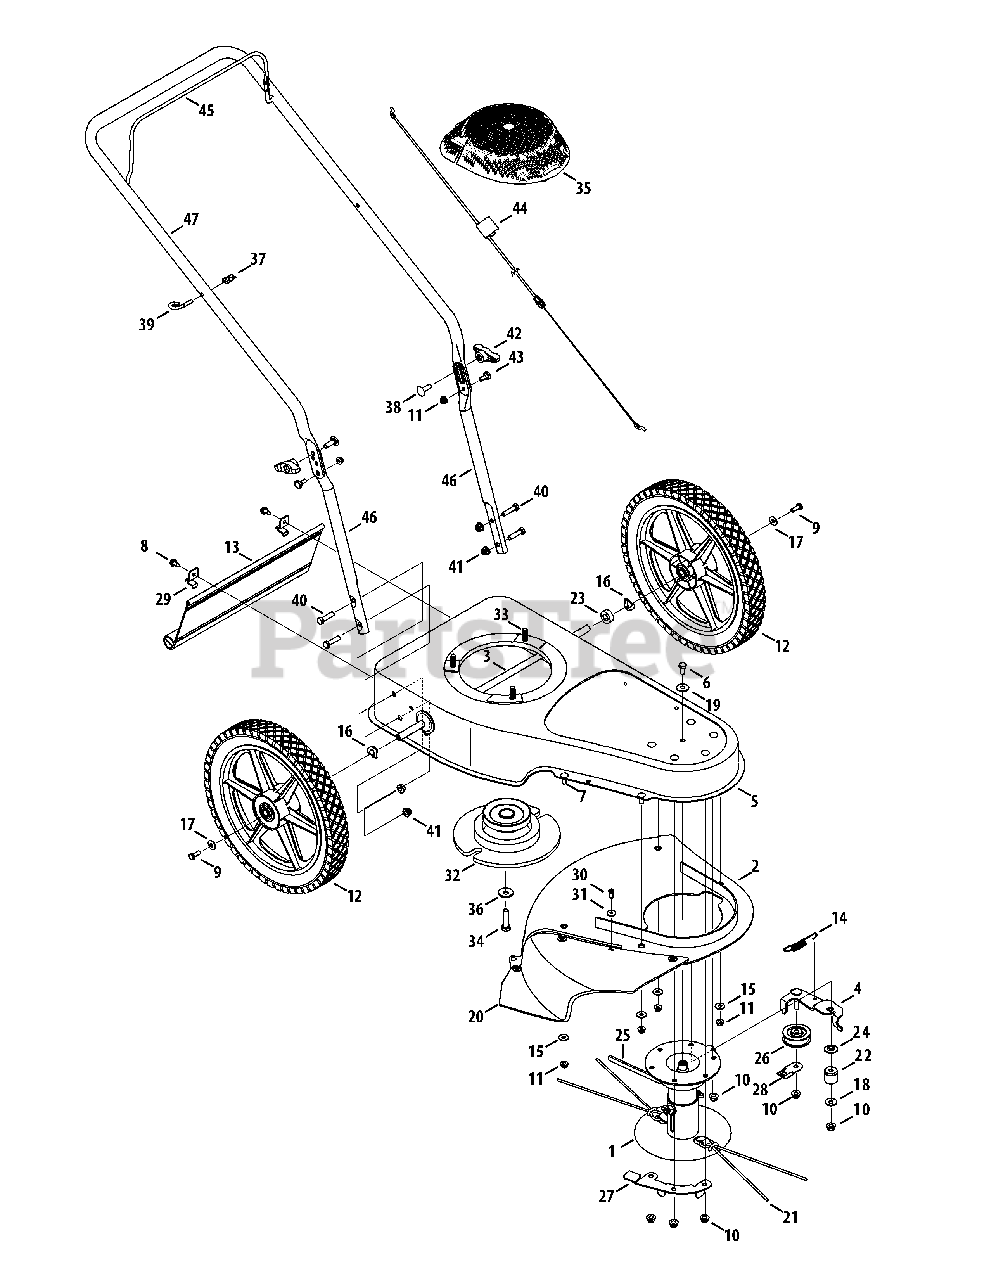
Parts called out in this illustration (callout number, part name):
1	Spindle Assembly
2	Deflector Assembly, Trimmer
3	Axle Assembly, Trimmer
4	Bracket Assembly, Idler Trimmer
5	Deck Assembly, Trimmer
6	Hex Screw, 5/16-24, .625, Gr5, Std
7	Screw, Carriage, 1/4-20, .75, Gr5
8	Screw, Self-tapping, 1/4-20 x .625
9	Hex Screw, 1/4-20, .75, Gr5, Std
10	Nut, Flange Lock, 5/16-18, GrF
11	Nut, Flange Lock, 1/4-20, GrF
12	Wheel, 14 x 1.75, Gray
13	Trailshield, 5.85 x 14.50
14	Spring, Extension, .50 OD x 3.375
15	Washer, Flat, .280 x .740 x .063
16	Washer, Spring, .500 x 1.00 x .022
17	Washer, Belle, .265 x .750 x .060
18	Washer, Flat, .343 x .880 x .062
19	Washer, Belle, .325 x .930 x .045
20	Flap, Deflector, String Trimmer
21	Line, Trimmer, .155, 10-pack
22	P/M Spacer
23	Spacer, .51 ID x 1.00 OD x .38
24	Spacer, Idler, Trimmer
25	V-Belt
26	Pulley, Idler, Trimmer
29	Hinge Clip, Trailshield
30	Screw, HL, #12-16, .625, Panphi
31	Washer, Flat, .194 x .62 x .063
32	Pulley/Flywheel
33	Sems Screw, 3/8-16, 1.0,
34	Hex Screw, 3/8-24, 1.25, Gr8
35	Cover, Shroud
36	Washer, Belle, .396 x 1.14 x .095
37	Knob, Handle
38	Screw, Carriage, 5/16-18, 1.00, Gr5
39	Eye Bolt, 1/4-20
40	Hex Screw, 3/8-16, 1.25, Gr5, Std
41	Nut,, Flange Lock, 3/8-16, GRF
42	Knob, Wing, 5/16-18, Black
43	Shoulder Screw, .375 x .148 x1/4-20
44	Control Cable, 48"
46	Handle, Lower
47	Handle, Upper
